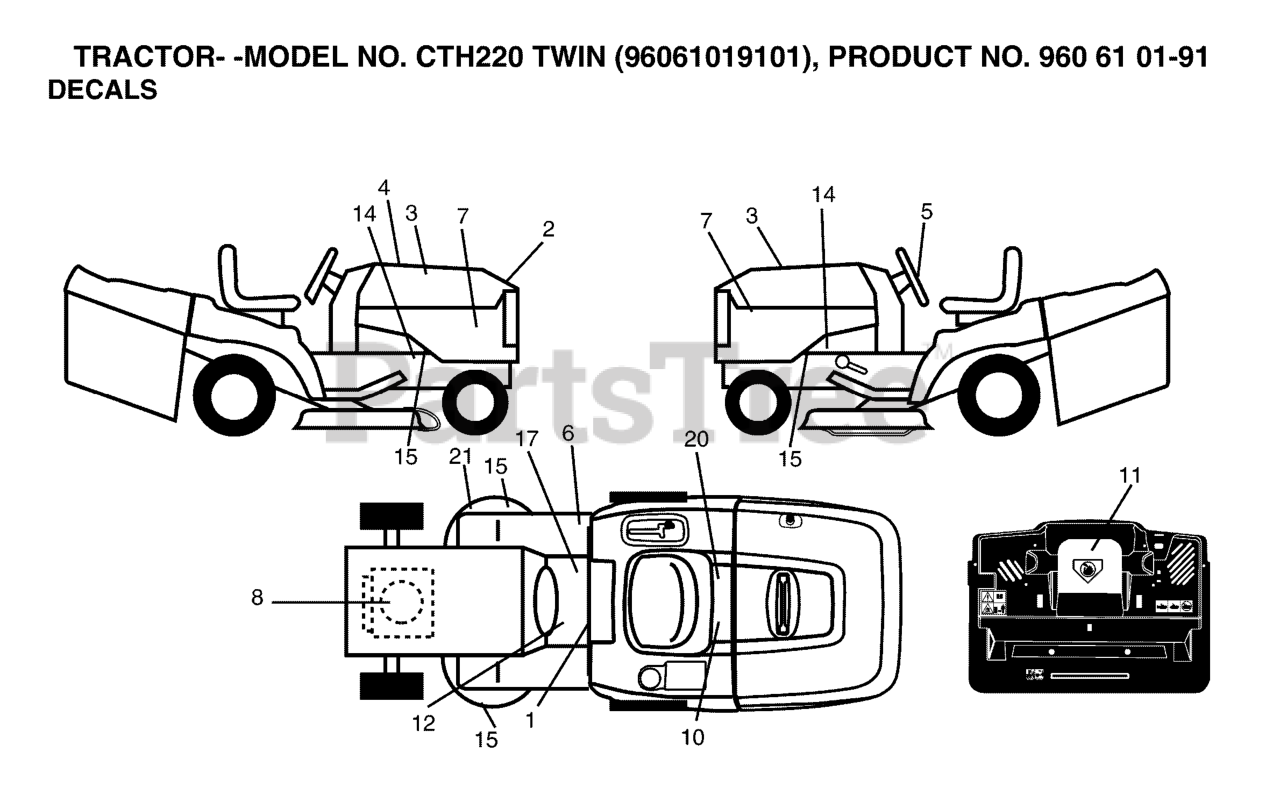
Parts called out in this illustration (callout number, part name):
1	LABEL
2	DECAL.HOOD.TOP.INSERT.
3	DECAL.HOOD.NAMELOGO.HUSQ
5	DECAL.WHEEL.STRG.LGN.H
6	Decal, Fender 100 DB/CE
8	DECAL
10	DECAL BTRY SYMBOLS
11	DECAL.INTERNATIONL.CUTFINGER
12	DECAL
17	DECAL PARK BRAKE
20	DECAL.BYPASS.FENDER.CRD.LT.YT
